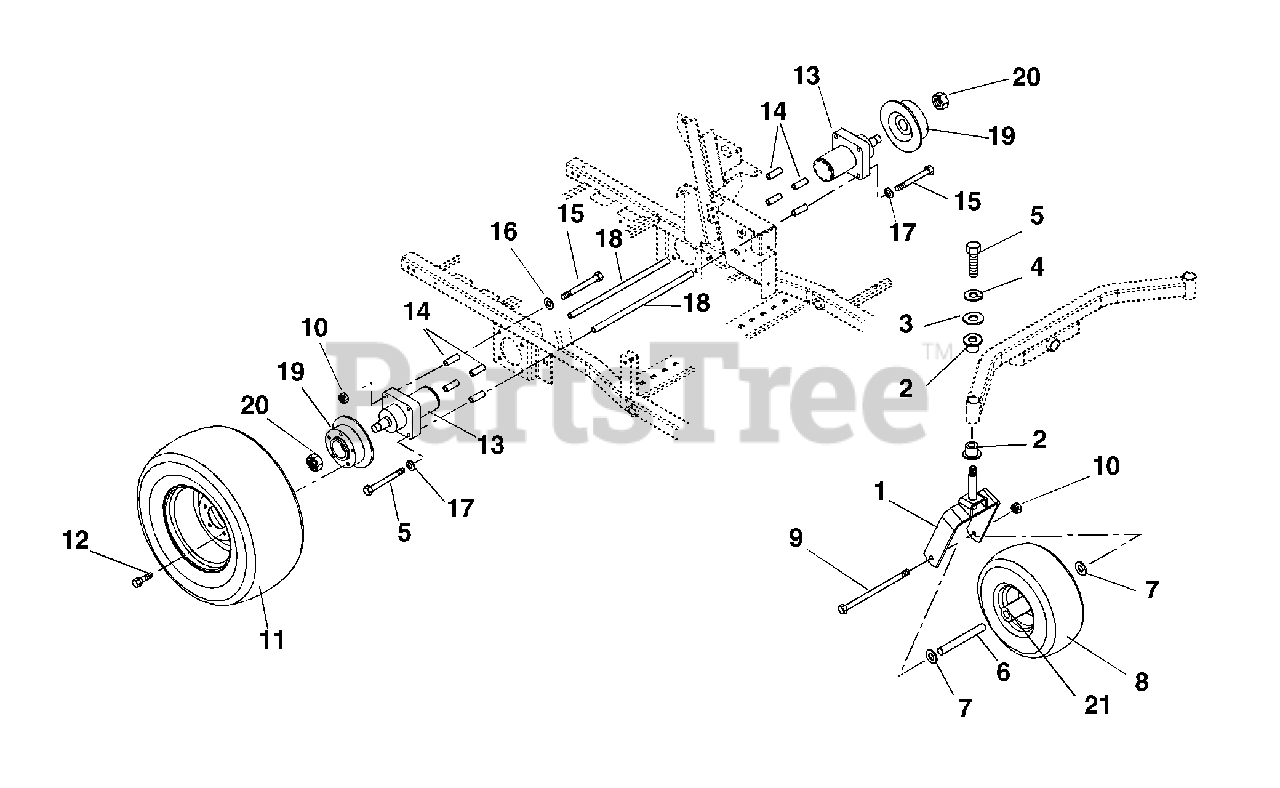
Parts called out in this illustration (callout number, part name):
1	Fork-Front
2	Bushing, Flange 1.020 x 1.385 x .75 x 1.75
3	Washer-Flat-Steel .380 x 1.50 x .125
4	Washer-Locking .38 x .094
5	Bolt-Hex .38-16 x 1.25 Grade 5
6	Spacer-Wheel
7	Washer-Flat-Steel .515 x 1.625 x .250
8	Wheel/Tire Assembly
8	Tire, 15 x 6-6
9	Bolt-Hex .50-13 x 9.00 Grade 5
10	Nut-Locking-Center .50-13
11	Wheel-Tire 23 x 8.50 Multi-Trac
11	Tire 23 x 8.50-12 Multitrac C/S
12	Bolt-Lug .50-20 x 1.62
13	Hydraulic Wheel Motor
14	Bushing-Sleeve .513 x .748 x 2.129
15	Bolt-Hex .50-13 x 5.00 Grade 8
16	Spacer .500 x .750 x .321
17	Washer-Locking .50 x .125
18	Rod-Motor Connecting
19	Hub and Disc
20	Nut -Lock Jam Patch
21	Bearing, 25MM I.D. x 52MM O.D. x 15MM
